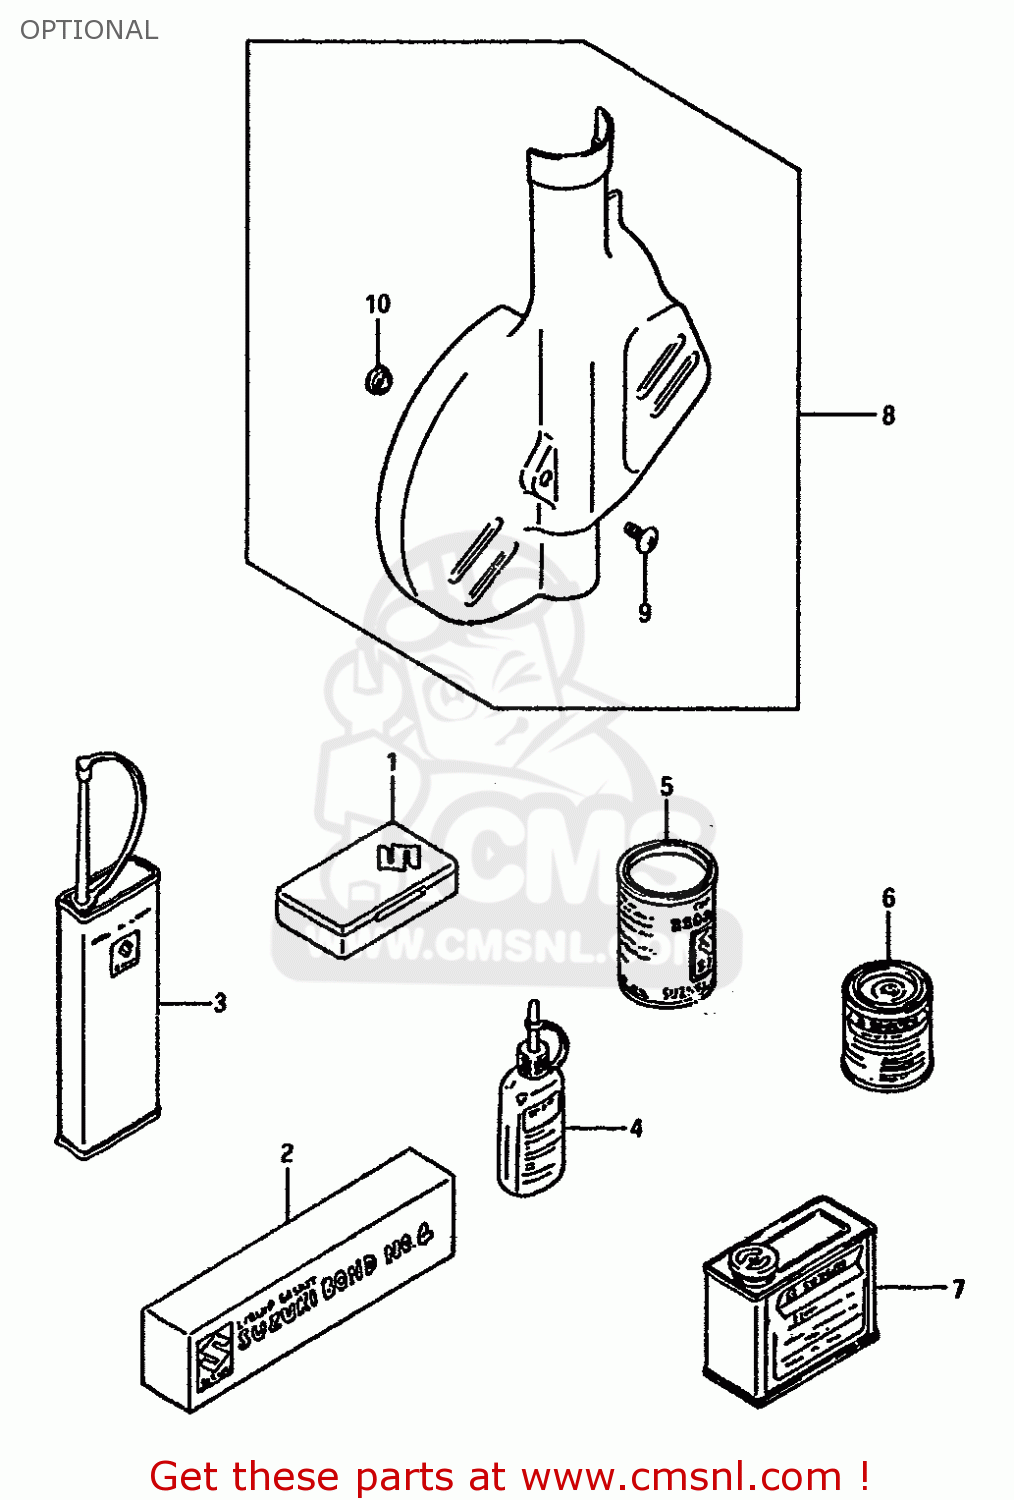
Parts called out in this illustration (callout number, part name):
1	TUBE REPARING TOOL
2	BOND 1104
3	THREAD LOCK NO.1401 CLEAR 200G
4	THREAD LOCK NO
5	GREASE(C)EP2 LITHIUM 150G
6	PAINT (ACCENT BLUE)
7	PAINT (ACCENT BLUE)
8	COVER,FRONT DISC
9	SCREW(8X12)
10	WASHER
